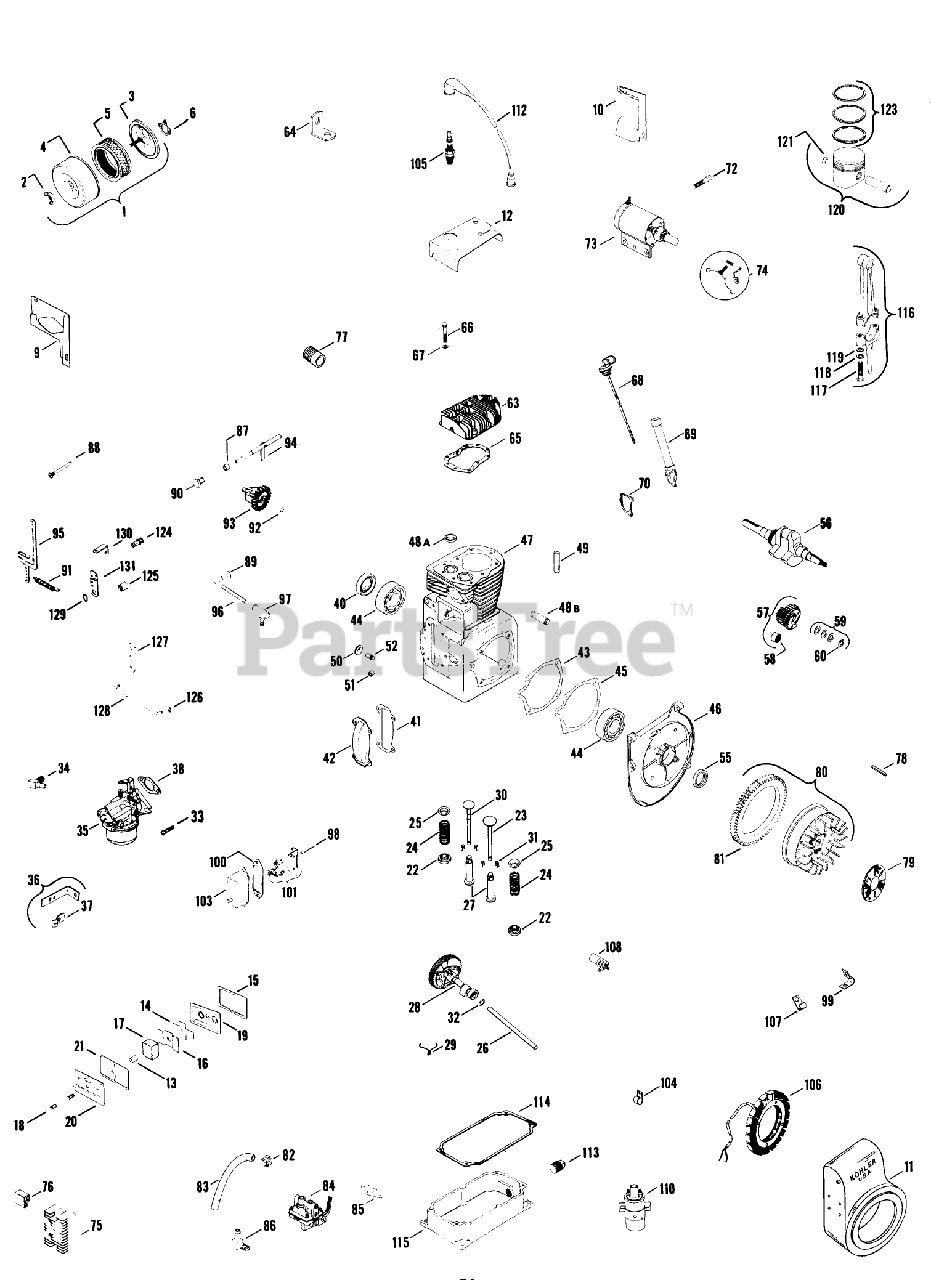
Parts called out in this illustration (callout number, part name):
1	Cleaner-Air Assembly
2	Nut-Wing
3	Base-Air Cleaner
4	Cover-Air Cleaner
5	Element
6	Gasket-Air Horn
9	BaffLe side air
10	Baffle cylinder
11	Housing-Blower
12	Baffle-Head
13	Seal
14	Reed
15	Gasket
16	Baffle breather
17	Filter Breather
18	Stud, valve cover
19	Plate
20	Cover valve
21	Gasket
22	Retainer-Spring
23	Valve-Intake
24	Spring
25	Retainer-Spring
26	Pin (Service)
27	Tappet
28	Camshaft-assembly
29	Spring-Actuating
30	Valve, exhaust
31	Keeper, Valve
32	Spacer
33	Screw sitd. hd.
34	Elbow
35	Carburetor-assembly
35	Repairkit
36	Bracket, choke
37	Clip
38	Gasket
40	Seal rear oil
41	Gasket
42	Cover
43	Gasket
44	Ball Bearing
45	Gasket
46	Plate Bearing
47	Block, cylinder-assembly ( Use B-237416 Mini block )
48A	Insert
48B	Shaft
49	Guide Valve
50	Plug
51	Bearing
52	Shaft-Govemor
55	Seal, Front OiI
56	Crankshaft
57	Gear
58	Bearing,needle
59	Kit-Spacer
60	Retainer
63	Belt Guide
64	Lift Cable
65	Gasket-Head
66	Screw
66	Screw-H.C.
67	Washer
68	Dipstick
69	Tube, fill
70	Gasket
72	Screw
73	Starter
74	Kit, Brush Spring
75	Regulator
76	Connector
77	Nipple
77	Washer
77	Nut
78	Key
79	Screen grass
80	Flywheel-Assembly
81	Gear Ring
82	Clamp
83	Line Fuel
84	Pump, fuel
85	Gasket, pump
86	Elbow
87	Spacer
88	Pin-GovemorStop
89	Retainer Rod
90	Bushing
91	Spring-Governor
92	Washer
93	Gear, Governor
94	Shaft, Governor
95	Lever, Governor
96	Rod ball joint
97	Ball Joint
98	Rod, breaker
99	Clip
100	Gasket, Cover
101	Breaker
103	Cover breaker
104	Clip
105	Plug, spark
106	Stator
107	Clip
108	Condenser
110	Coil
112	Kit, Hi-Tension
113	Plug
114	Gasket
115	Base, oil pan
116	Rod, Connecting
116	Rod-Conn. Assy. (.010)
117	Screw, connecting rod
118	Washer
119	Washer
120	Piston-assembly (Std.) (Includes pin retainers)
120	Piston-assembly (.003) (Includes pin retainers)
120	Piston-assembly (.010) (Includes pin retainers)
120	Piston-assembly (.020) (Includes pin retainers)
120	Piston-assembly (.030) (Includes pin retainers)
121	Pin, Retainer
123	Ring set-Std. .003 (Svc.)
123	Ring set-.010 (Service)
123	Ring set-.020 (Service)
123	Ring set-.030 (Service)
124	Clamp, swivel wire
125	Spacer
126	Retainer Rod
127	Bellcrank
128	Rod, throttle
129	Washer
130	Spacer
131	Bracket
